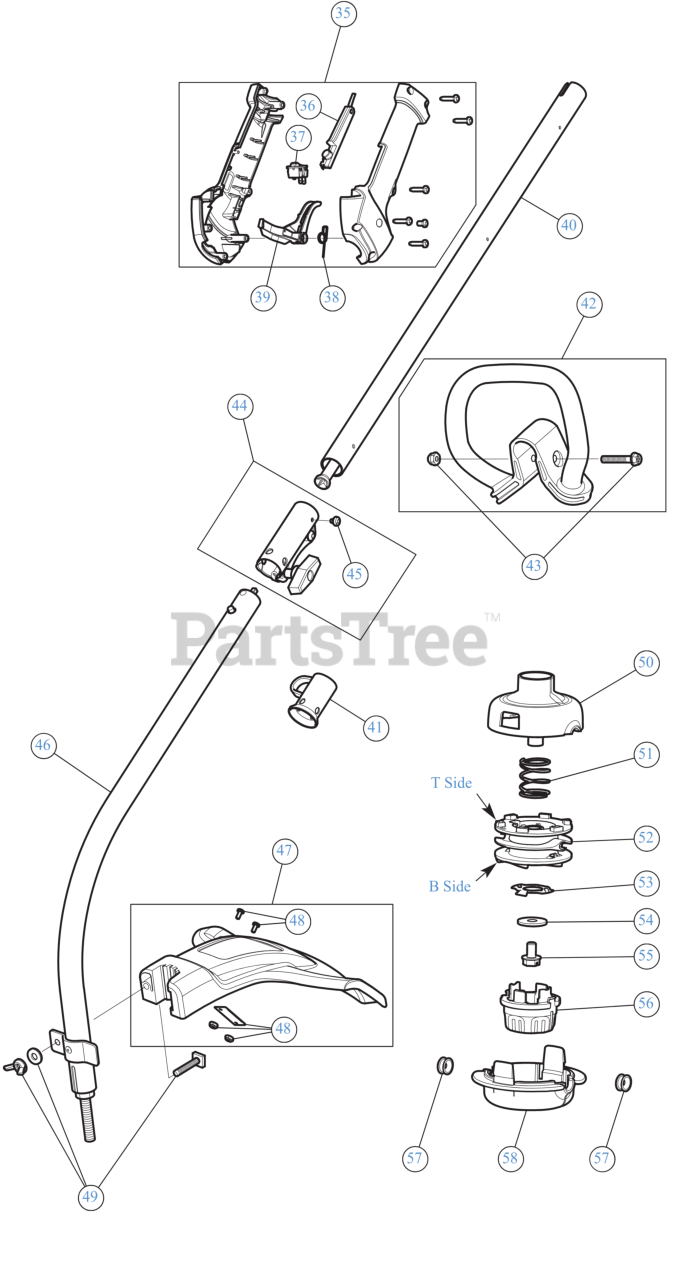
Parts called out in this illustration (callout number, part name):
35	THROTTLE GRIP ASSEMBLY
36	LEVER LOCK OUT
37	SW, MOMENTARY ON/O
38	TRIGGER SPRING
39	THROTTLE TRIGGER
40	BOOM ASSEMBLY UPR
41	HANGER
42	D-HANDLE
43	BOLT 1/4-20X1 1/2
44	SPLIT BOOM COUPLER KIT
45	SCREW, 10-32X.250 TA
46	BOOM ASM LWR
47	GUARD ASSEMBLY
48	ASSEMBLY, BLADE
49	BLADE GUARD MOUNTING HARDWARE
50	OUTER SPOOL
51	SPRING-SPOOL
52	INNER REEL
53	SPOOL RETAINER
54	FLAT WASHER 1.0 OD:.331 ID
55	BOLT 5/16-18
56	BUMP KNOB
57	EYELET
58	SPOOL CAP
